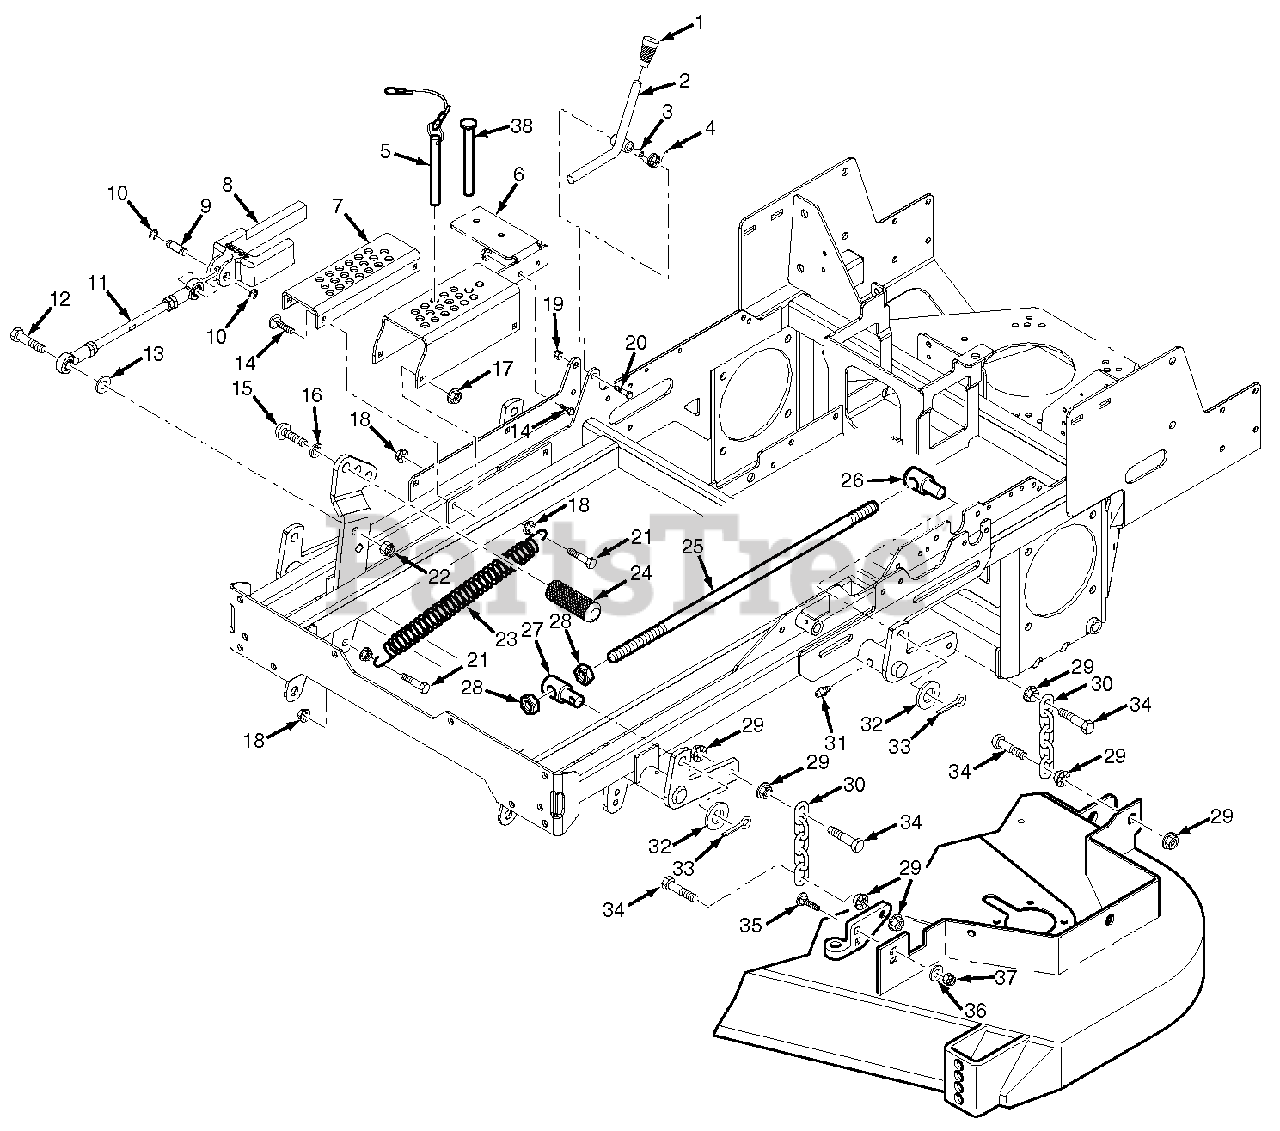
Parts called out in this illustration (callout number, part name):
1	Hood Assembly w/Decals
1	Hood Assembly w/Decals - Kohler ECV860
2	Flatwasher, 3/8-.406 x .812 x .065
3	Lock, Hood Latch
4	Spring, Hood Latch
5	Latch, Hood
6	Bolt, Shoulder
7	Bolt, Hex Head 3/8-16 x 1-3/4"
8	Spacer, Hood
9	Disc, Anti-Friction
10	Screw, #8-32 x 1/2"
11	Belt Guard, Rear
11	Belt Guard, Rear - Kohler
12	Spring Clip
13	Nut, Elastic Stop #8-32
14	Bolt, Carriage 1/4-20 x 1/2"
15	Bolt, Carriage 1/4-20 x 3/4"
16	Nut, Serrated Flange 1/4-20
17	Hinge, Belt Cover
18	ROPS Heatshield
18	ROPS Heatshield - Kohler
19	Bumper, Rubber
20	Button Head Capscrew, Torx 3/8-16 x 1"
21	Bumper, Rear
22	Nut, Serrated Flange 3/8-16
23	Bolt, Hex Head 3/8-16 x 1"
24	Flatwasher, 3/8-.406 x 1.5 x 7 Ga.
25	Nut, Elastic Stop 3/8-16
26	Mount Weldment, Hood
26	Mount Weldment, Hood - Kohler
27	Brace, Hood Support
28	Bolt, Hex Head 3/8-16 x 1-1/4"
29	SCZ Skid Plate, Kawasaki FX
29	SCZ Skid Plate, Kohler
30	Mounting Bracket, Fuel Tank Rear
31	Nut, Serrated Flange 5/16-18
32	Bolt, Carriage 5/16-18 x 3/4"
33	U-Nut, 3/8-16
34	Mounting Bracket, Fuel Tank Front
35	Bolt, Hex Head 1/4-20 x 1"
36	U-Nut, 1/4-20
37	Bolt, Carriage 5/16-18 x 3/4"
38	Caster Support Weldment, 61V
38	Caster Support Weldment, 72V
39	Cap, Grease
40	Nut, Elastic Stop 1"-14
41	Bearing w/Race
42	Seal, 2" OD x 1.625 Bore
43	Yoke Weldment
44	Spacer, Caster Wheel
45	Sleeve, Caster Wheel
46	Caster Wheel Assy.
46	Bearing
46	Grease Fitting
47	Bolt, Hex Head 1/2-13 x 9-1/2"
48	Nut, Elastic Stop 1/2-13
49	Bolt, Hex Head 7/16-14 x 1-1/4"
50	Nut, Elastic Stop 7/16-14
51	Lockwasher, 7/16-" Spring
52	Mainframe Assy. w/Decals
53	Bolt, Hex Head 5/16-18 x 1"
53	Lockwasher, 5/16" Spring
54	Bolt, Hex Head 1/4-20 x 3/4"
55	Nut, Serrated Flange 1/4-20
56	Adjustment Bracket, Lower Cut Height
57	Adjustment Bracket, Upper Cut Height
58	Fan Cover, RH
59	Fan Cover, LH
60	Bolt, Hex Head 3/8-16 x 1"
61	Cover, Battery Box
62	Knob w/Stud
63	Nut, Push-On 3/8"
64	Nut, Serrated Flange 5/16-18
65	Pad, Rubber
66	Capscrew, Button Head 3/8-16 x 1-1/4"
